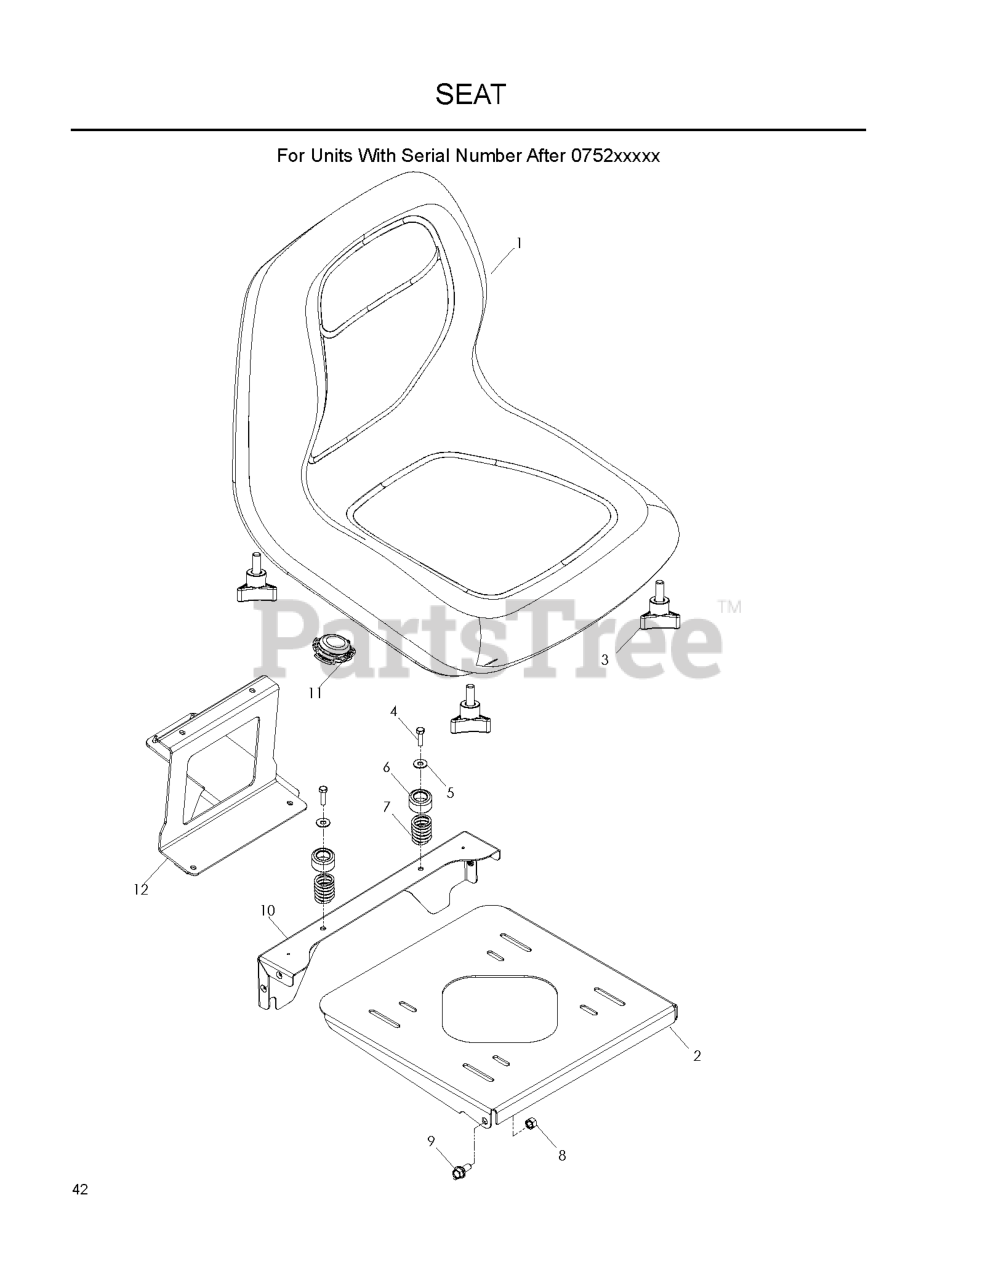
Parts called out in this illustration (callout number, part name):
1	SEAT.HIGHBACK.GREY.ZTR
2	SEAT MOUNT, BLACK
3	KNOB W/STUD
4	BOLT, SHOULDER
5	WASHER 3/8 FLAT
6	CAP, SPRING COVER
7	SPRING, SEAT
8	NUT 5/16 NYLOC
9	HCS 3/8C X 1 1/4 GR5
10	REAR SEAT SUPPORT ORANGE
11	SEAT SWITCH
12	BRACKET, FRONT SUPPORT Model 968999281 only
